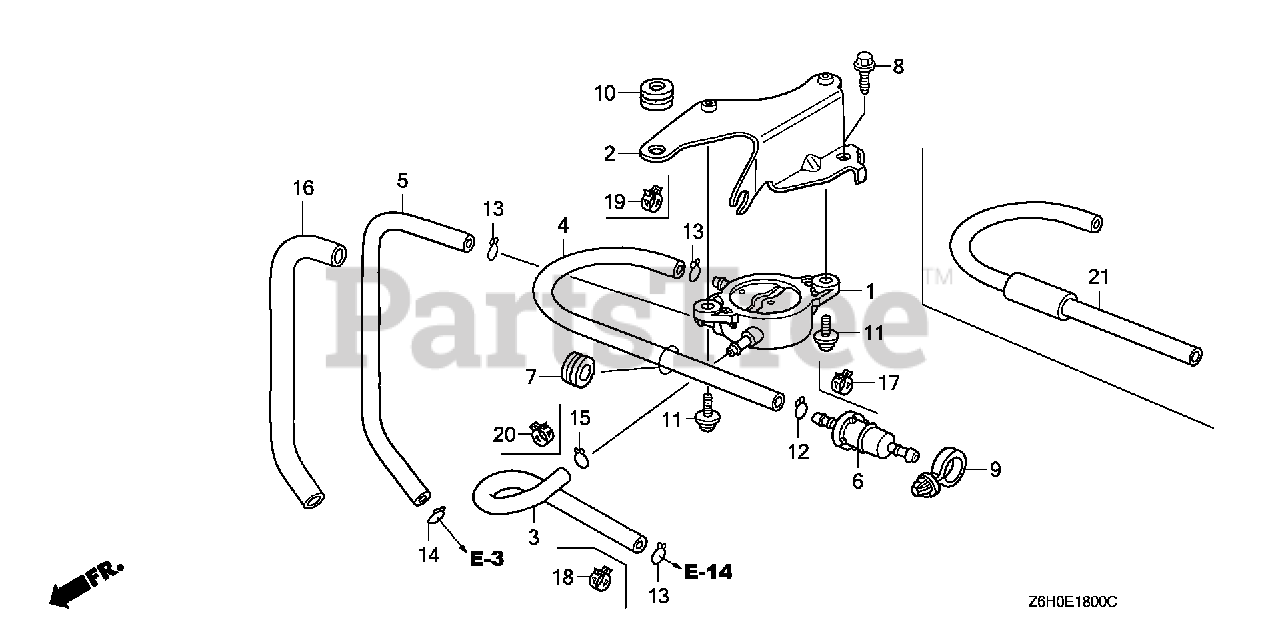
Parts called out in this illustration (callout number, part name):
1	PUMP ASSY., FUEL
2	STAY, FUEL PUMP
3	TUBE, FUEL (FKM)
3	TUBE, FUEL
4	TUBE B, FUEL
4	TUBE B, FUEL (FKM)
5	TUBE, DIAPHRAGM
6	STRAINER, FUEL
7	GROMMET, RESERVE TANK
8	BOLT, FLANGE (6X14) (CT200)
9	CLIP, WIRE HARNESS
10	GROMMET, PUMP STAY
11	SCREW-WASHER (6X16)
12	CLIP, TUBE (B8)
13	CLIP, TUBE (B10)
14	CLIP, TUBE (B8)
14	CLIP, TUBE (C9)
15	CLIP, TUBE (C11)
16	BULK HOSE, VINYL (9X11X3000) (9X11X150)
17	CLAMP, TUBE (D8)
18	CLAMP, TUBE (D10)
19	CLAMP, TUBE (D8.5)
20	CLAMP, TUBE (D10)
20	CLAMP, TUBE (D10.5)
21	TUBE B, FUEL (FKM)
